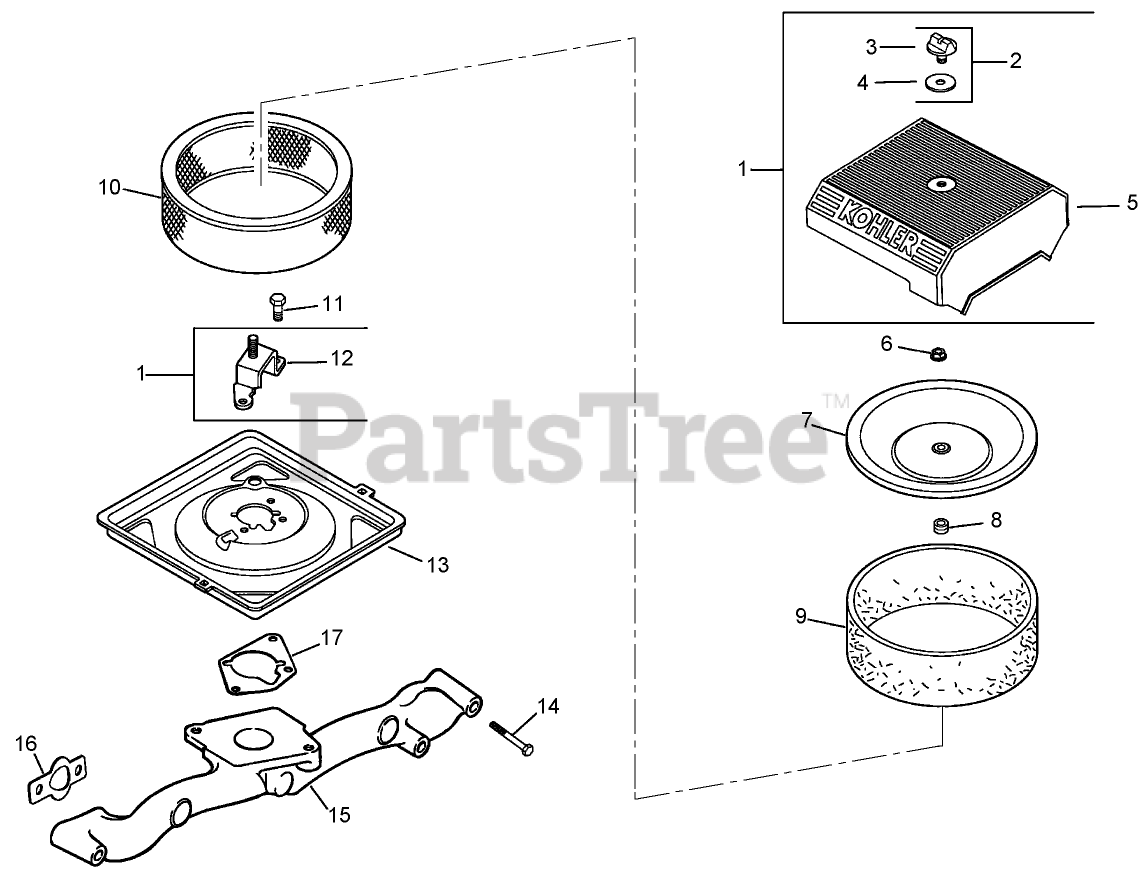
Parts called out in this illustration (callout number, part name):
1	Air Cleaner Cover Kit (Includes 2-5, 12)
2	Knob Kit (Includes 3, 4)
3	KNOB-COVER
4	O-RING
5	Cover-Cleaner, Air
6	NUT-FLANGE (M6X1.0)
7	COVER-AIR CLEANER, INNER
8	Seal
9	PRE-CLEANER
10	ELEMENT-FILTER, AIR
11	SCREW-FLANGE, THREAD FORMING (M6X1.0X16)
12	Bracket-Base, Air Cleaner
13	BASE-CLEANER, AIR
14	Screw-HF (M6x1.0x55)
15	Manifold-Intake
16	Gasket-Manifold, Intake
17	GASKET-BASE, AIR CLEANER
